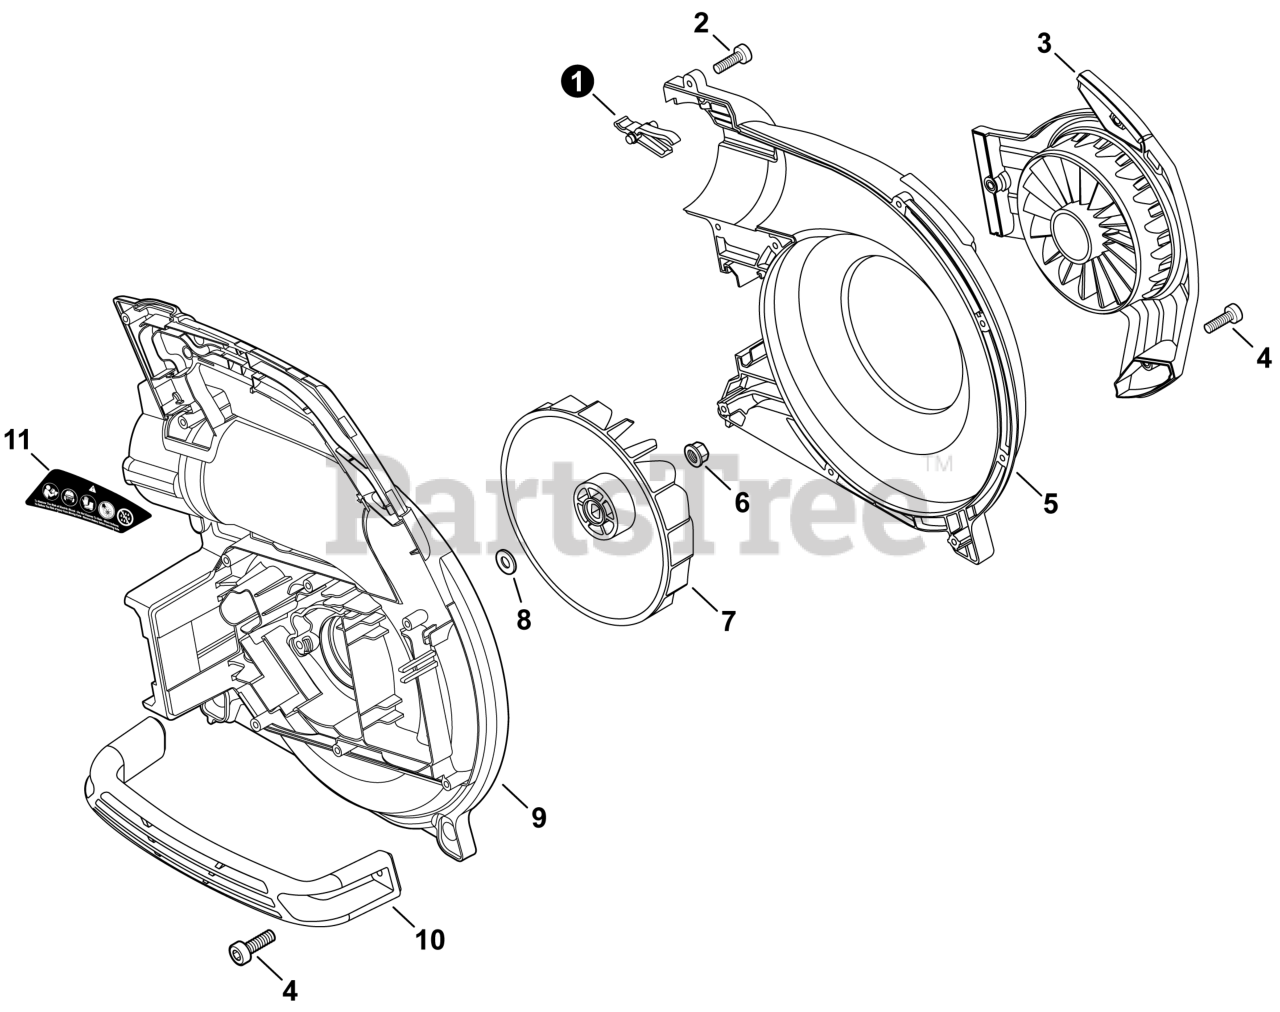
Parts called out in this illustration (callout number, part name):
1	LOCK, TUBE
2	BOLT, TORX 4x16
3	GUARD, DEBRIS
4	BOLT, TORX 5x20
5	COVER, FAN
6	NUT, FLANGE M8x1.25
7	FAN, BLOWER
8	WASHER 10.5x18x1.6
9	CASE, FAN
10	HANDLE, SUPPORT
11	LABEL - CAUTION
